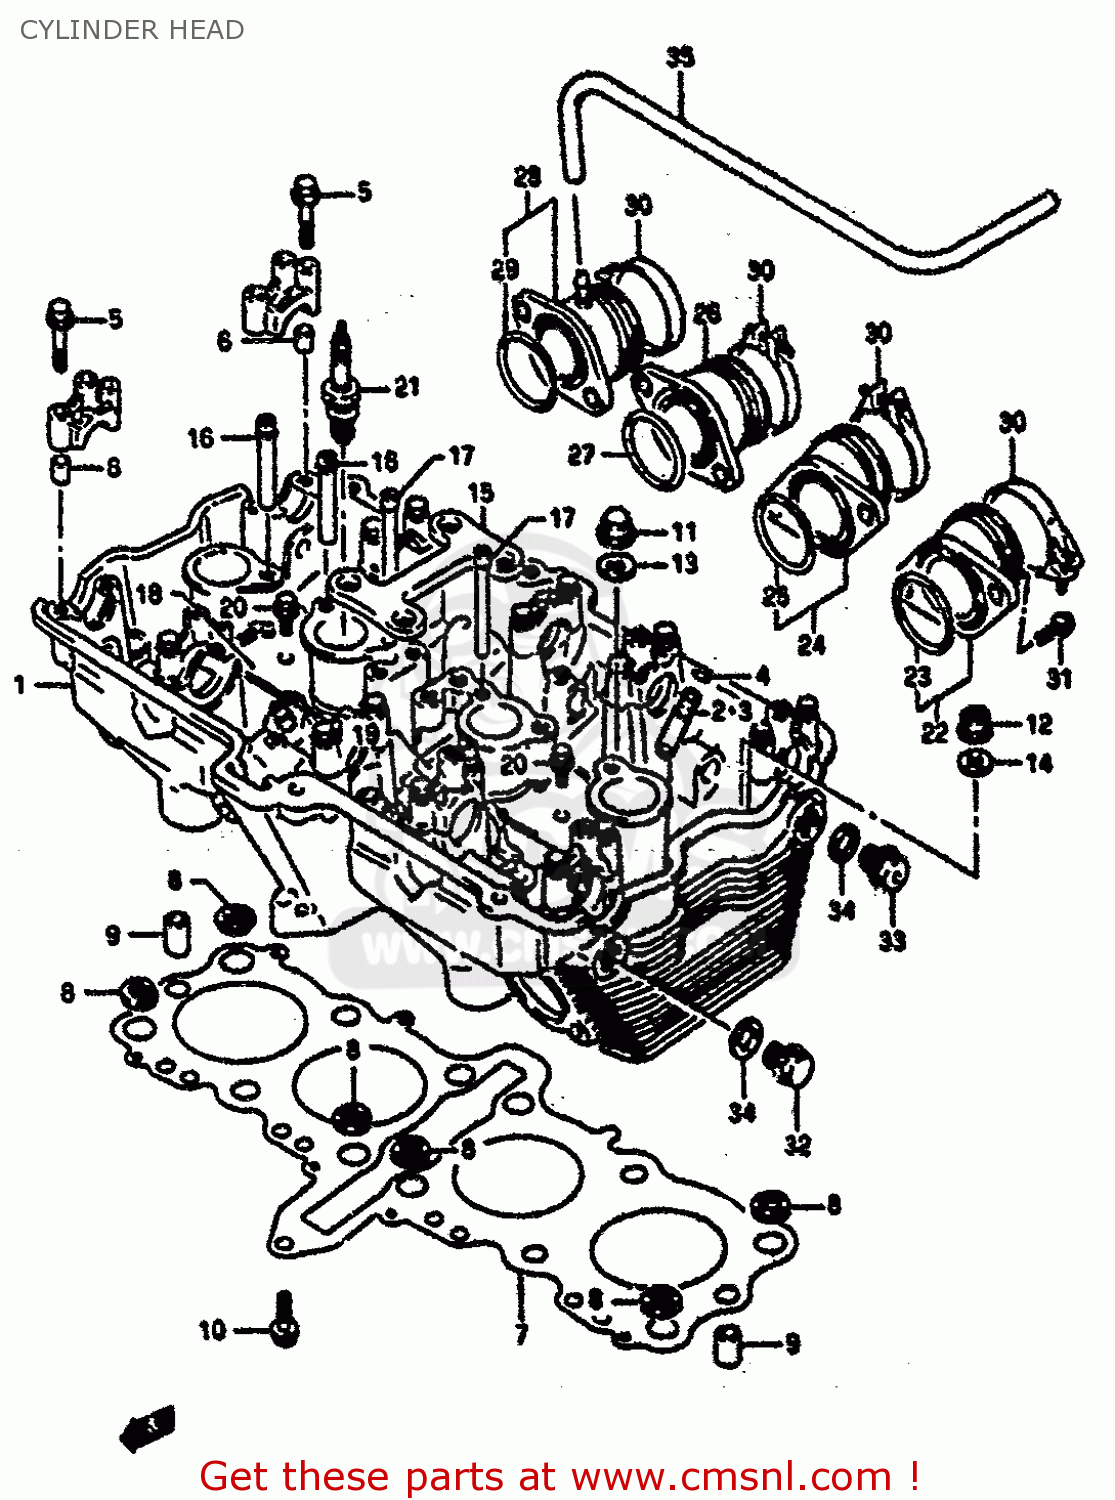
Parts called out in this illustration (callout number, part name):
1	HEAD ASSEMBLY,CYLINDER
2	GUIDE,VALVE
3	GUIDE,VALVE
4	RING,SNAP
5	BOLT(6X39)
6	PIN(6.2X8X11)
7	GASKET,CYLINDER HEAD (NAS)
8	O-RING,HEAD GASKET
9	PIN
10	BOLT
11	NUT
12	NUT
13	GASKET(10.2X20X2).3 (NAS)
14	WASHER (10.5X22X2.3)
15	PLATE,HEAD REINFORCEMENT
16	PIPE,OIL NO.1
17	PIPE,OIL NO.3
18	PLATE,OIL PIPE,R
19	PLATE,OIL PIPE,L
20	BOLT
21	PLUG,SPARK(JR9B)
22	PIPE,INTAKE NO.1
23	O RING(D:2.4,ID:39.7)
24	PIPE,INTAKE NO.2
25	O RING(D:2.4,ID:39.7)
26	PIPE,INTAKE NO.3
27	O RING(D:2.4,ID:39.7)
28	PIPE,INTAKE NO.4
29	O RING(D:2.4,ID:39.7)
30	CLAMP
31	SCREW
32	PLUG
33	PLUG
34	GASKET(14X19.2X2) (NAS)
35	HOSE
